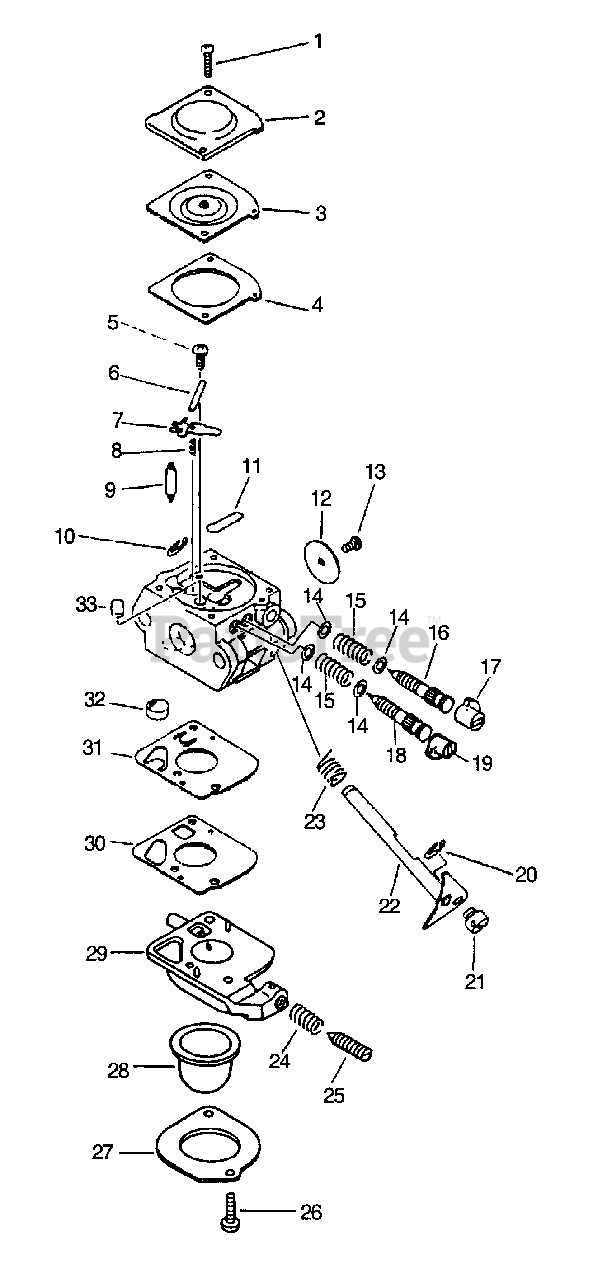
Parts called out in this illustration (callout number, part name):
2	COVER, METERING DIAPHRAGM
3	DIAPHRAGM, METERING
4	GASKET, METERING
6	PIN, METERING LEVER
7	LEVER, METERING
8	SPRING, METERING LEVER
9	VALVE, NEEDLE
11	PLUG, WELCH
12	VALVE, THROTTLE
15	SPRING, NEEDLE
16	NEEDLE, MIXTURE
17	CAP, LIMITER - WHITE
18	NEEDLE, HIGH SPEED
19	CAP, LIMITER - RED
22	SHAFT, THROTTLE
23	SPRING, THROTTLE RETURN
25	SCREW, THROTTLE ADJUST
27	RETAINER
28	BULB, PURGE
29	BODY ASSY, PURGE
32	STRAINER
33	NOZZLE, CHECK VALVE
